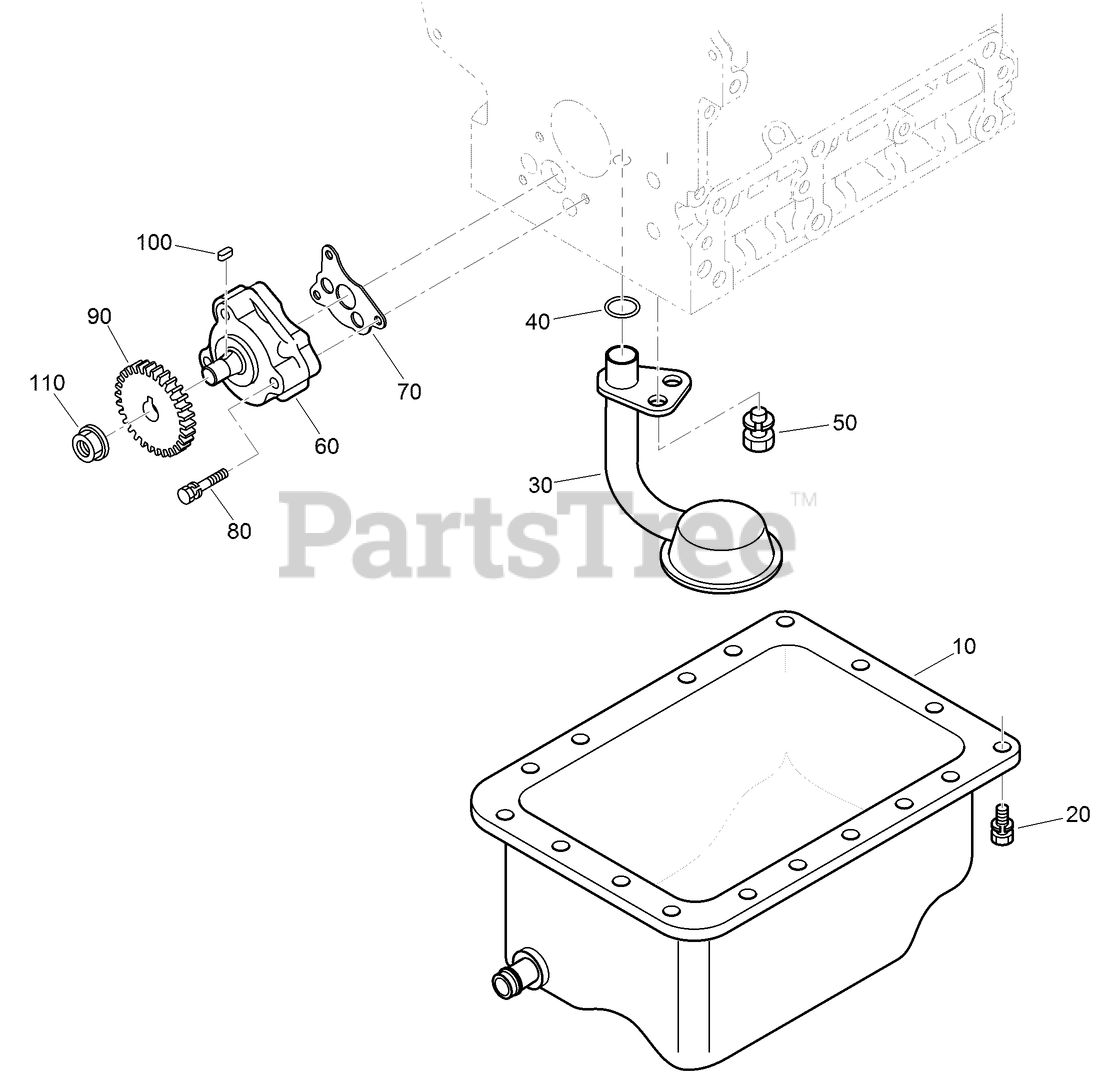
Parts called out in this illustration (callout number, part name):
10	PAN-OIL
30	STRAINER-PICKUP, OIL
40	O-RING
60	OIL PUMP ASM
70	GASKET-PUMP, OIL
90	GEAR-DRIVE, OIL PUMP
100	KEY-FEATHER
110	NUT-FLANGE
